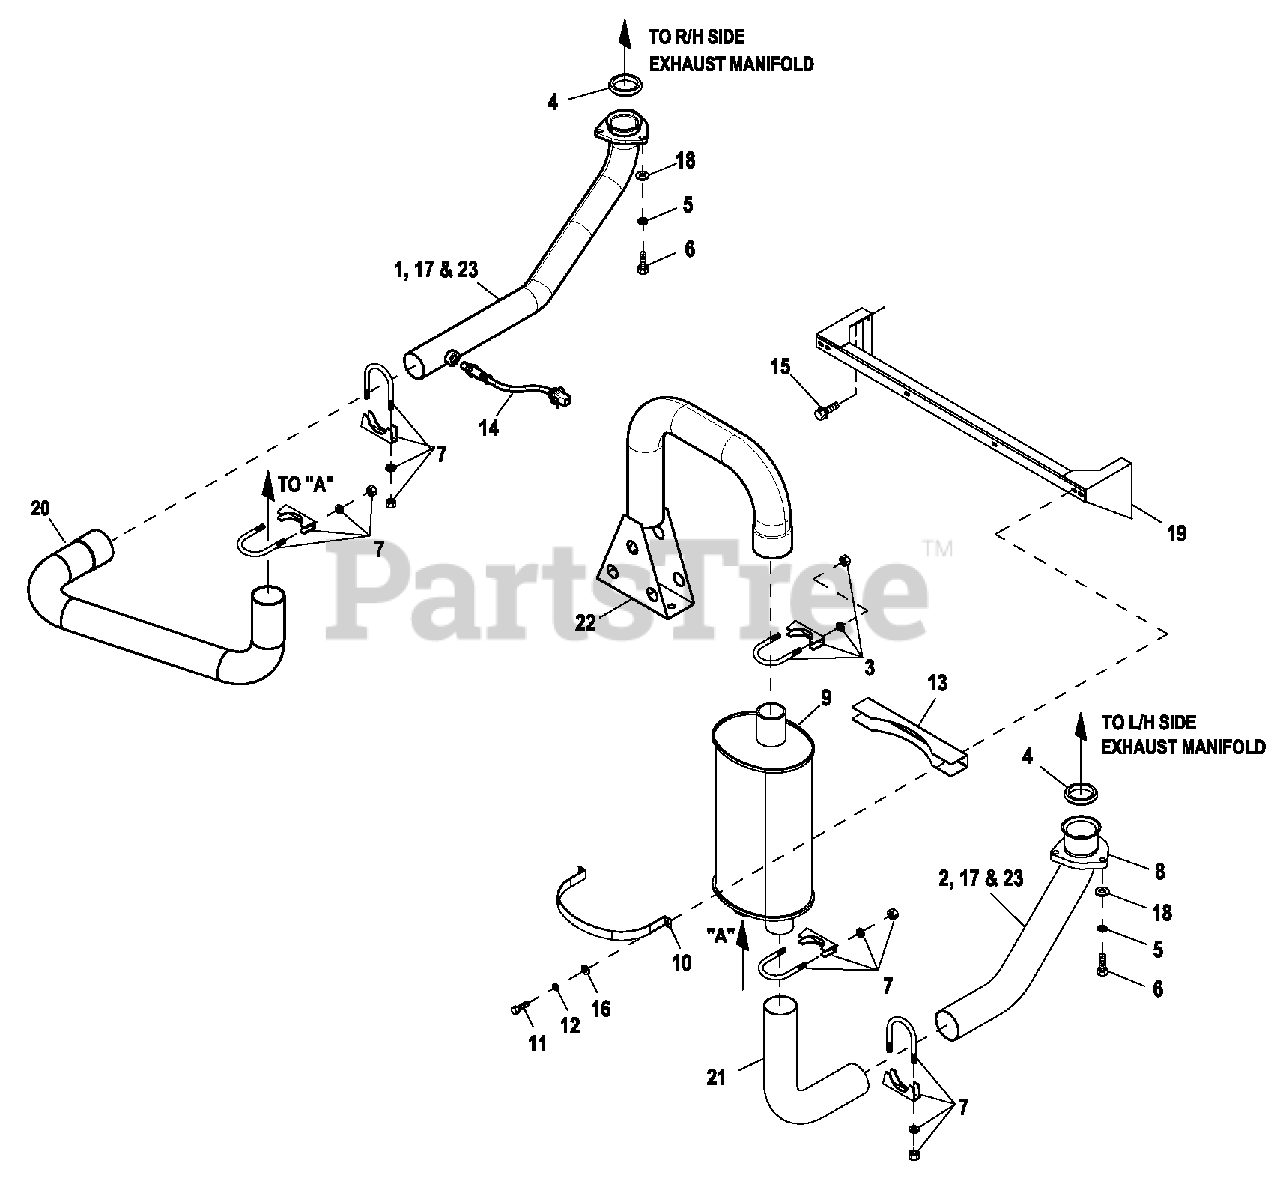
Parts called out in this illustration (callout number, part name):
1	ASSY PIPE EXH MANF 5.4L C2 EM (6.8L 70KW)
2	PIPE, EXH MANIFOLD 5.4L C2 LH (6.8L 70KW)
3	BOLT U 3/8-16X3.25
4	RING GASKET, 2.5DIA
5	WASHER LOCKM10 SS
6	SCREW HHC M10-1.5X 50 SS FTH
7	BOLT U 3/8-16X2.62
8	FLANGE, EXHAUST
9	MUFFLER CATALYST
10	MUFFLER STRAP
11	SCREW HHC M6-1.0 X 25 C8.8
12	WASHER LOCK M6-1/4
13	MUFFLER BRACKET STIFFENER
14	SENSOR OXYGEN
15	SCREW HWHT M6-1 X 16 N WA Z/JS
16	WASHER FLAT 1/4-M6 ZINC
18	WASHER FLAT 3/8 SS
19	BRACKET MUFFLER
20	PIPE, EXHAUST RH CPL C2
21	PIPE ELBOW EXHAUST MUFFLER
22	WELDMENT EXHAUST DIFFUSER 3"
